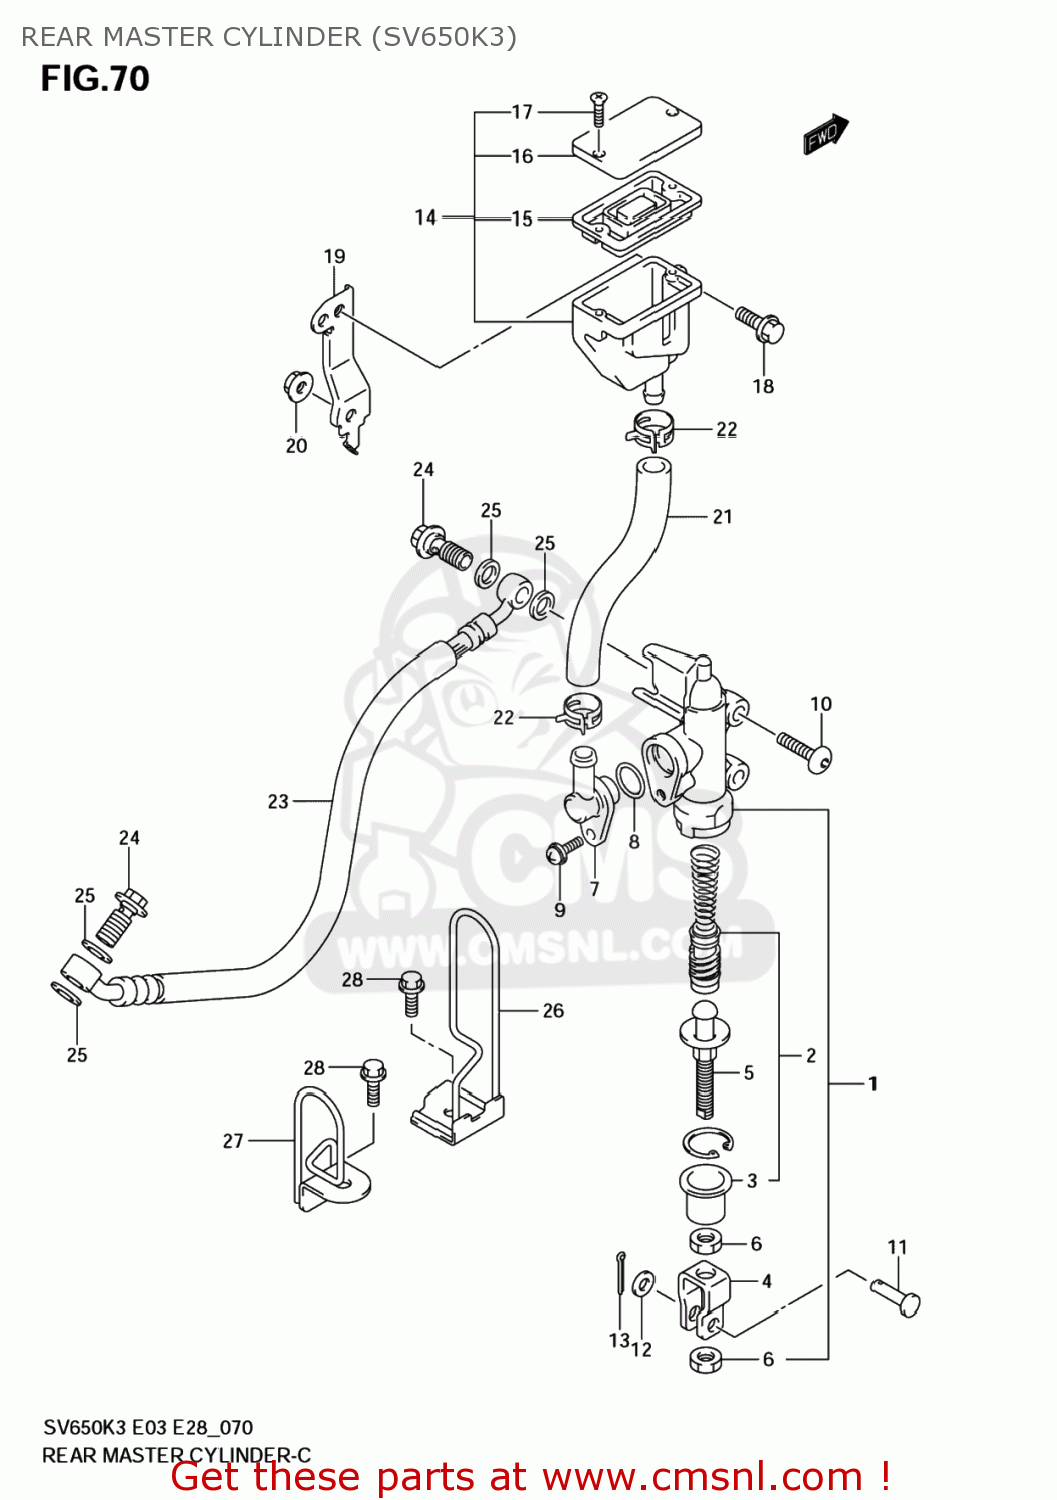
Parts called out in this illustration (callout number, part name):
1	CYLINDER ASSY,RR MASTER
2	PISTON/CUP SET
3	BOOT
4	YOKE
5	ROD,PUSH
6	NUT
7	CONNECTOR
8	O RING
9	SCREW
10	SCREW(6X20)
11	PIN(6X18.2)
12	WASHER
13	PIN
14	TANK ASSY,RR RESERVOIR
15	DIAPHRAGM
16	CAP
17	SCREW
18	BOLT(6X12)
19	BRACKET,RR RESERVOIR TANK
20	NUT
21	HOSE,RR RESERVOIR TANK
22	CLIP
23	HOSE,RR BRAKE
24	BOLT UNION
25	WASHER(10X15X1.5)
26	GUIDE,RR BRAKE HOSE NO.1
27	GUIDE,RR BRAKE HOSE NO.2
28	BOLT
